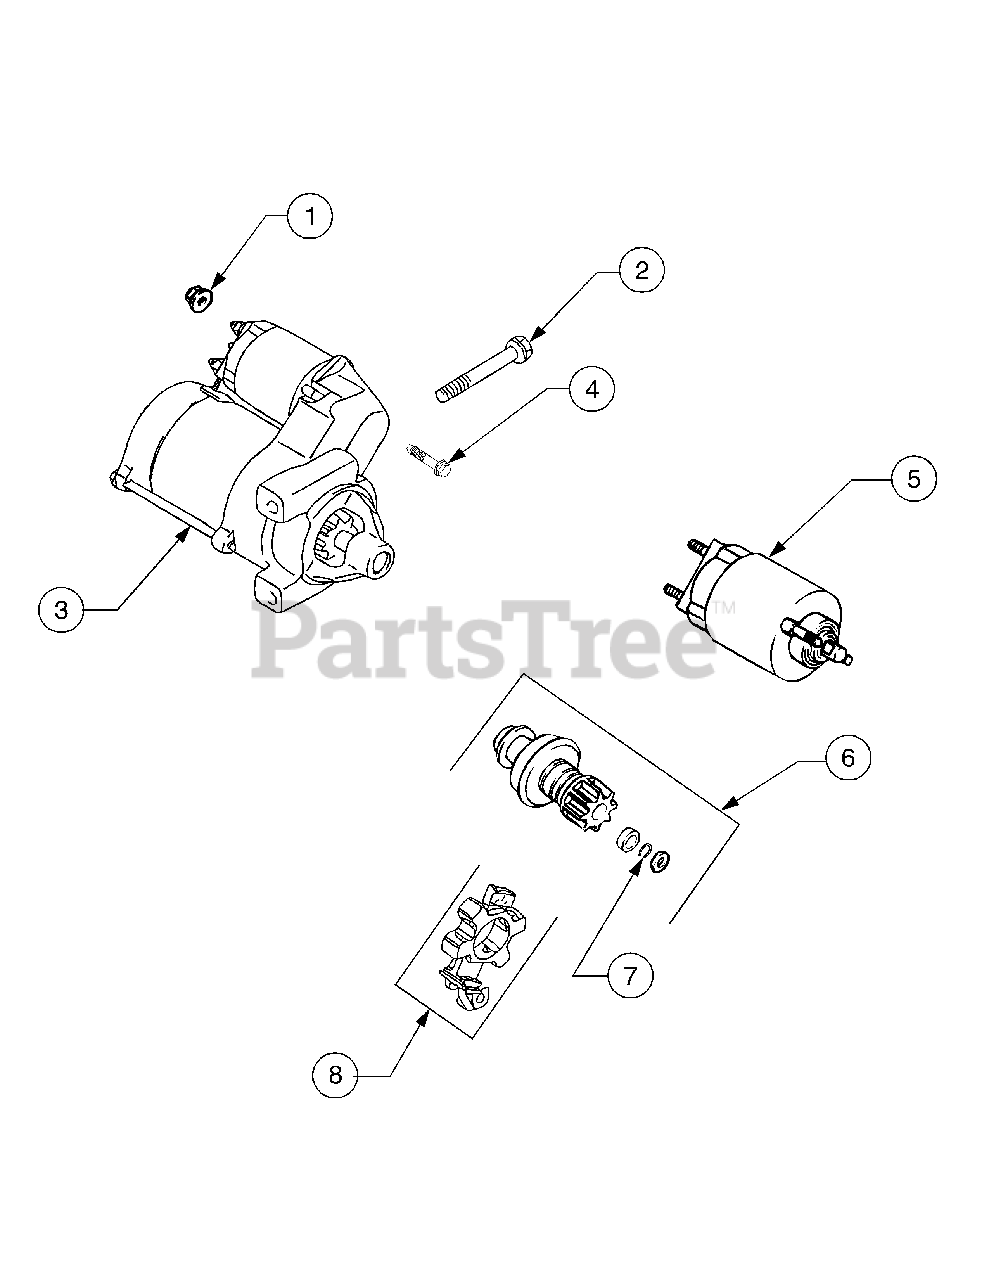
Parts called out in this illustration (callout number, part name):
1	Nut, Hex Flange M8 x 1.25"
2	Screw, Hex Flange M8 x 1.25 x 80
3	Starter, Solenoid Shift Assembly .(Includes 4-8)
4	Screw, External Torx Hd.
5	Kit, Solenoid
6	Kit, Pinion Drive (Includes 7)
7	Ring, Retainer
